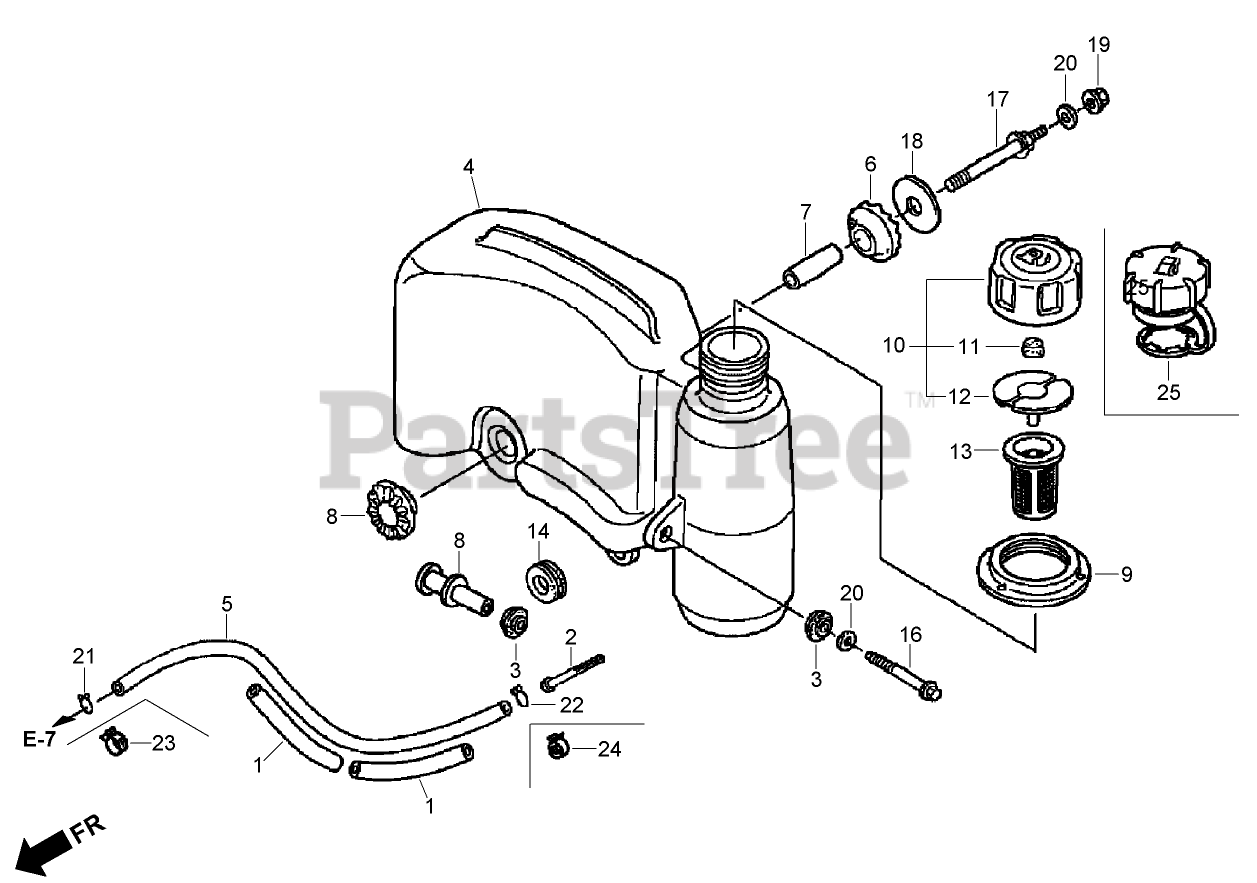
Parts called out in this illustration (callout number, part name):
1	SUPPORTER-RUBBER (107 mm)
2	FILTER-FUEL
3	RUBBER-SETTING, TANK
4	TANK-FUEL (Engine Serial No. Up To 1036455)
4	TANK-FUEL
5	TUBE-FUEL (Engine Serial No. Up To 1011283)
5	TUBE-FUEL (FKM) (Engine Serial No. From 1011284)
6	RUBBER B-MOUNTING, TANK
7	COLLAR-SET, TANK
8	COLLAR-TANK
9	RUBBER-MOUNTING, TANK (Engine Serial No. Up To 1036455)
10	FUEL TANK CAP ASM
11	Sponge-BREATHER, Fuel Cap
12	GASKET-CAP, FUEL
13	GAUGE-LEVEL, FUEL
14	CUSHION-FENDER, R R
16	BOLT-FLANGE (6X47) (C T200)
17	BOLT-STAY, TANK
18	WASHER-MOUNTING, TANK
19	NUT-FLANGE (6 mm)
20	WASHER-PLAIN (6 mm)
21	CLIP-TUBE (B8)
22	CLIP-TUBE (C11) (engine serial numbers up to 6901760)
23	CLAMP-TUBE (D8) (engine serial numbers starting at 3698327)
24	CLAMP-TUBE (D105) (Engine Serial No. From 1011284)
25	FUEL TANK CAP ASM
